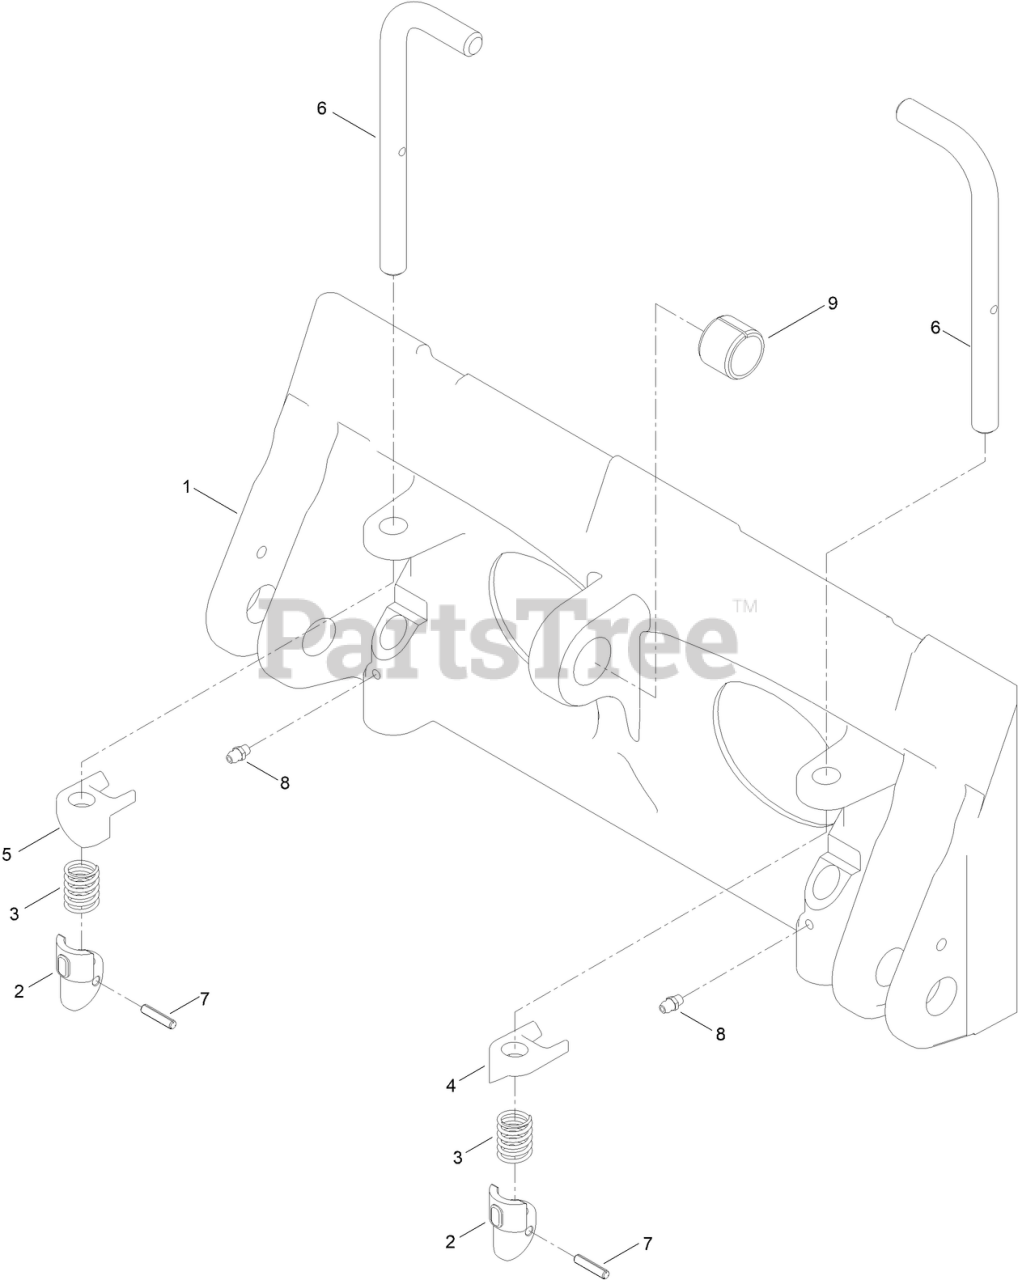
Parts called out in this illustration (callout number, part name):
1	MOUNT-QTACH
3	SPRING-COMPRESSION
4	STOP-RH
5	STOP-LH
6	PIN-LOCKING
7	PIN-GROOVED
8	FITTING-GREASE
9	BUSHING-TENSION
